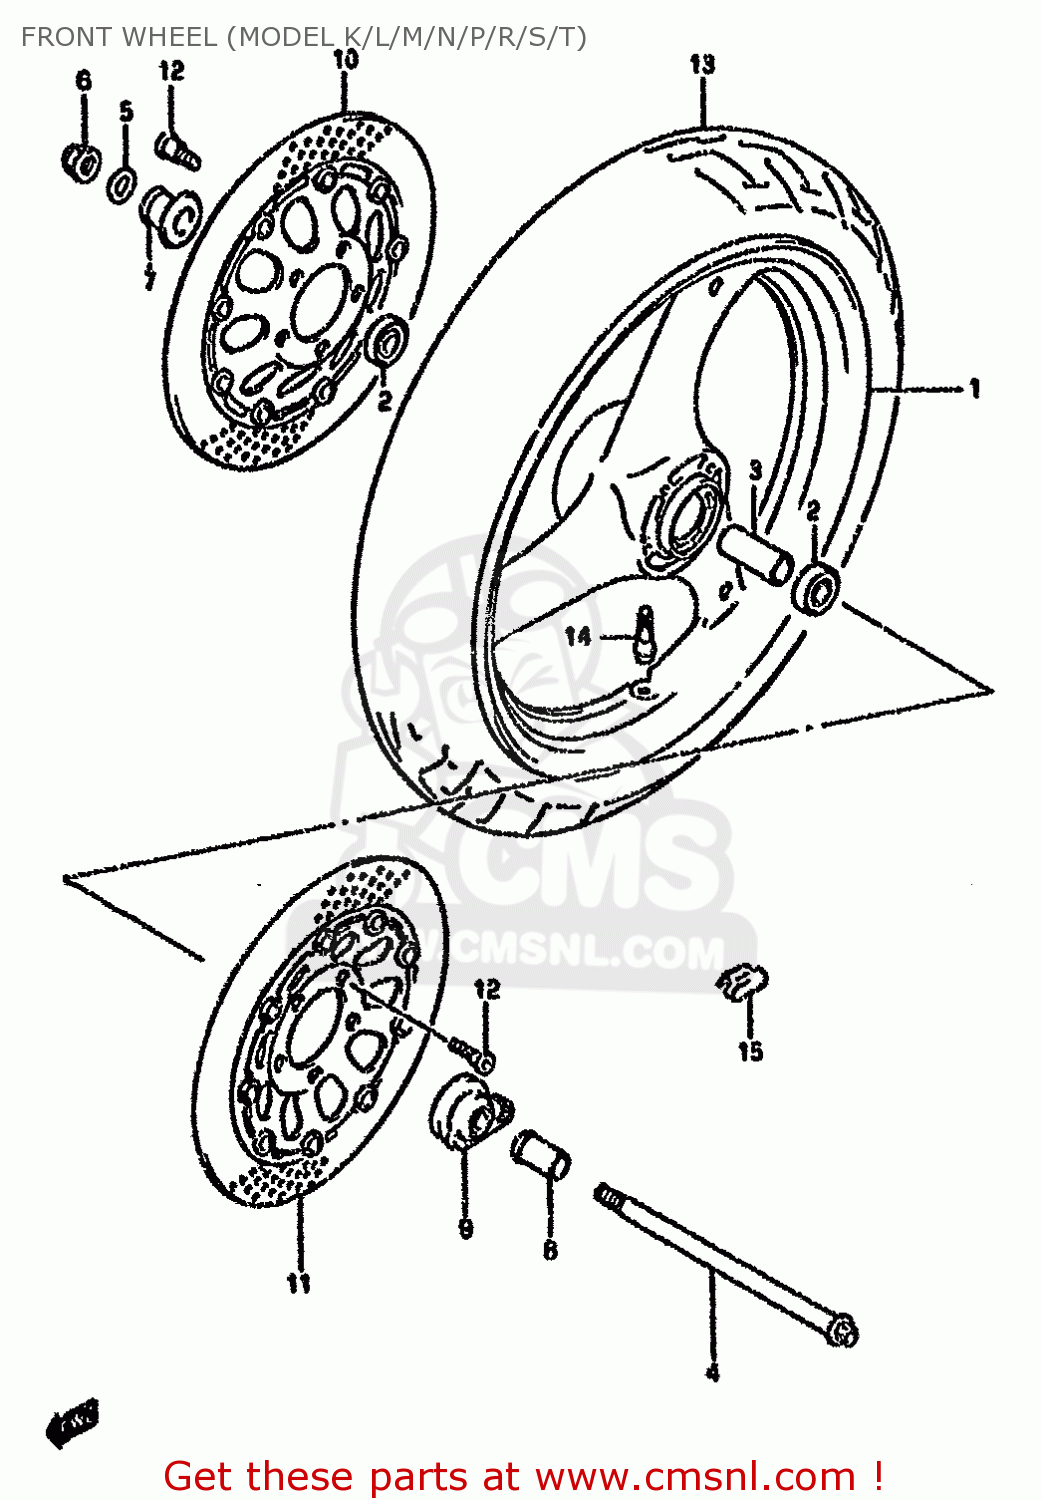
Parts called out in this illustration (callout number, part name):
1	WHEEL,FRONT (MT3.00X17)
2	BEARING
3	SPACER(15.3X21.7X63)
4	AXLE,FR
5	WASHER
6	NUT
7	SPACER,FR AXLE
8	SPACER,FR AXLE,L
9	BOX ASSEMBLY,SPEEDOMETER GEAR
10	DISC,BRAKE
11	DISC,BRAKE
12	BOLT 8X33
13	TIRE,FRONT 110/80-17.5
14	VALVE,TIRE
15	BALANCER,WHEEL
